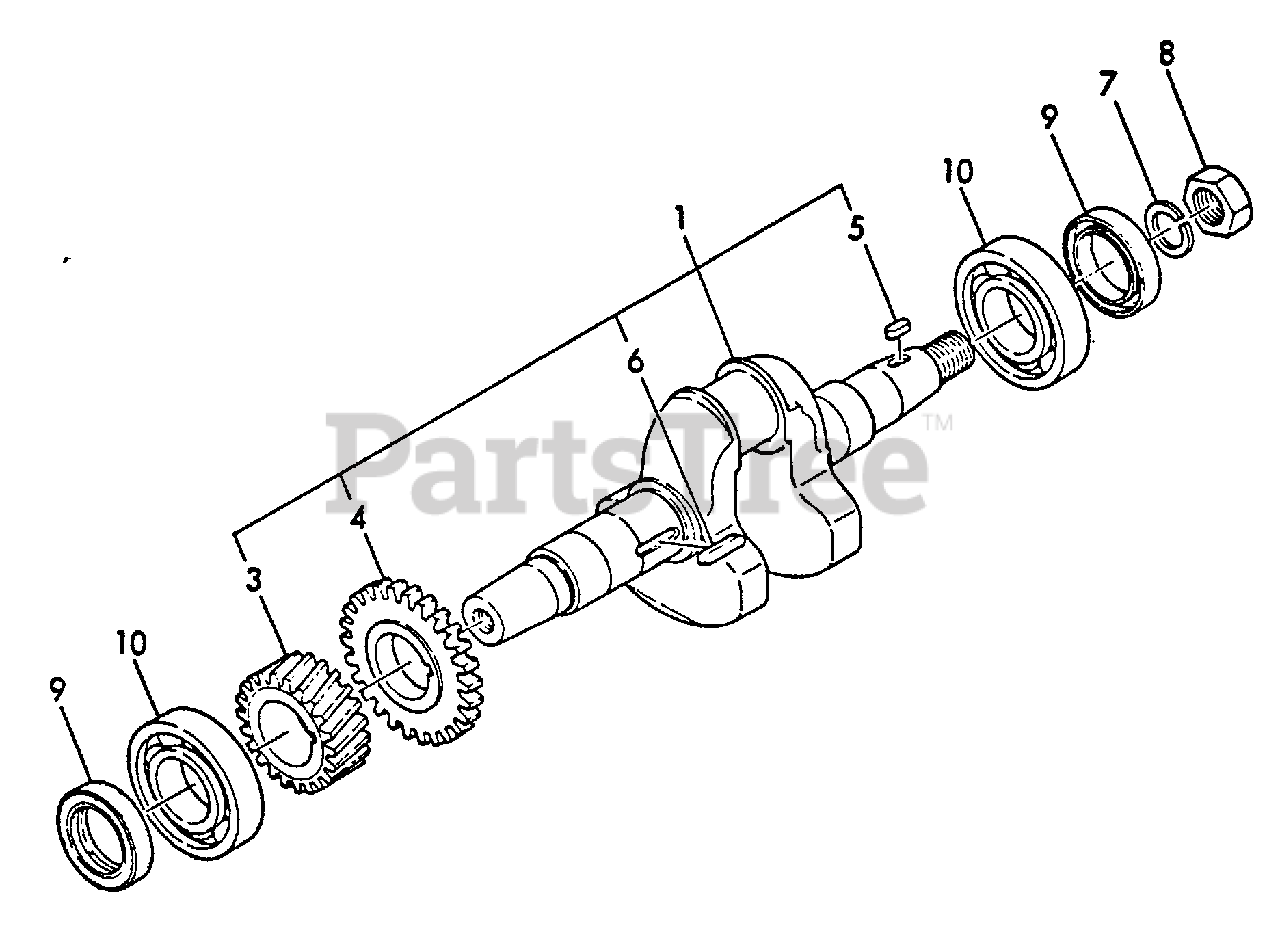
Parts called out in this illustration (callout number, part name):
1	CRANKSHAFT ASSY
3	GEAR, CRANKSHAFT
4	GEAR, BALANCER
5	KEY - 4×10
6	KEY 4×24
7	LOCKWASHER - 10
8	NUT - 16
9	SEAL, OIL
10	BEARING, BALL 6206C4
